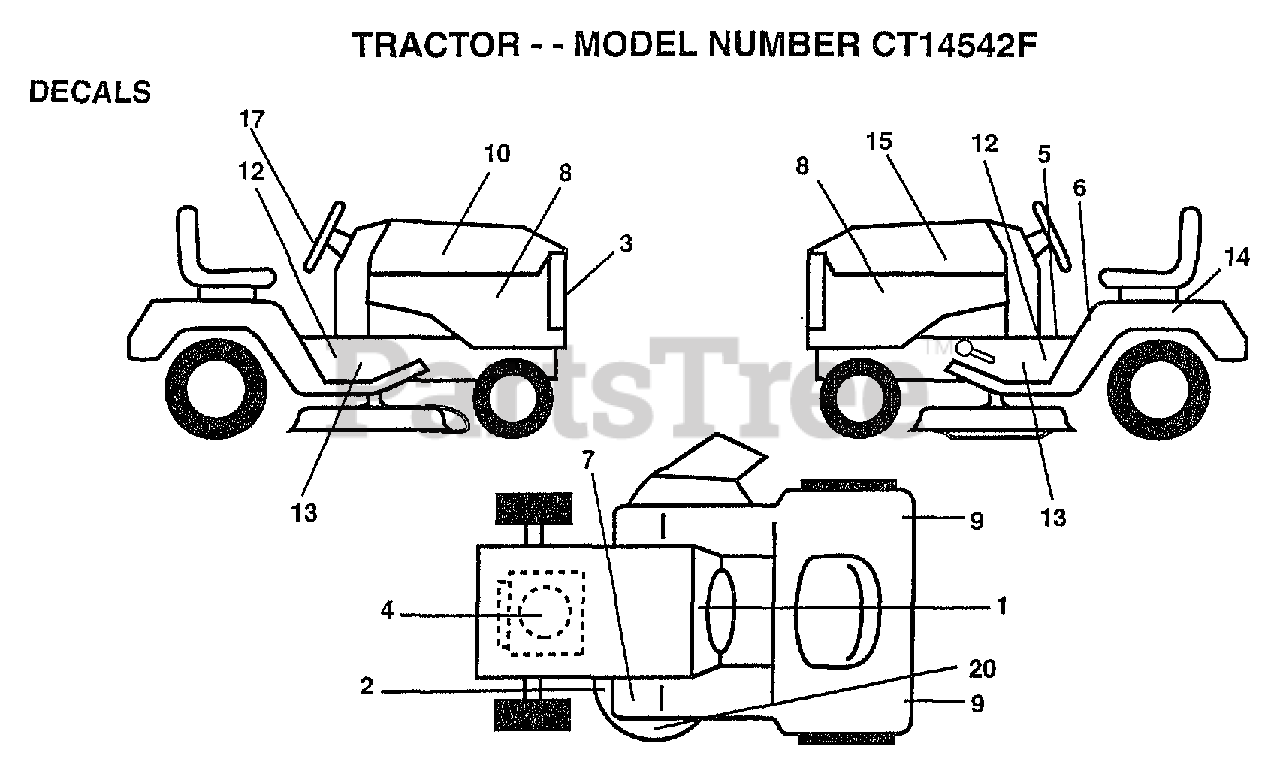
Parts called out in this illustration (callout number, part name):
1	"DECAL-OPER,GEAR D"
2	"DECAL-SCHEM,BELT"
3	DECAL GRILLE
4	DECAL, ENGINE
5	DECAL BRAK PARK
6	"DECAL DANGER,FEND"
8	DECAL SIDE PANEL
9	REFLECTOR-TAIL YT
10	DECAL HOOD RH
13	DECAL SIDE PANEL
14	DECAL.BATRY.3-3908
15	DECAL HOOD LH
17	DECAL INST STG WH
20	"DECAL,ENVIRO DECK"
